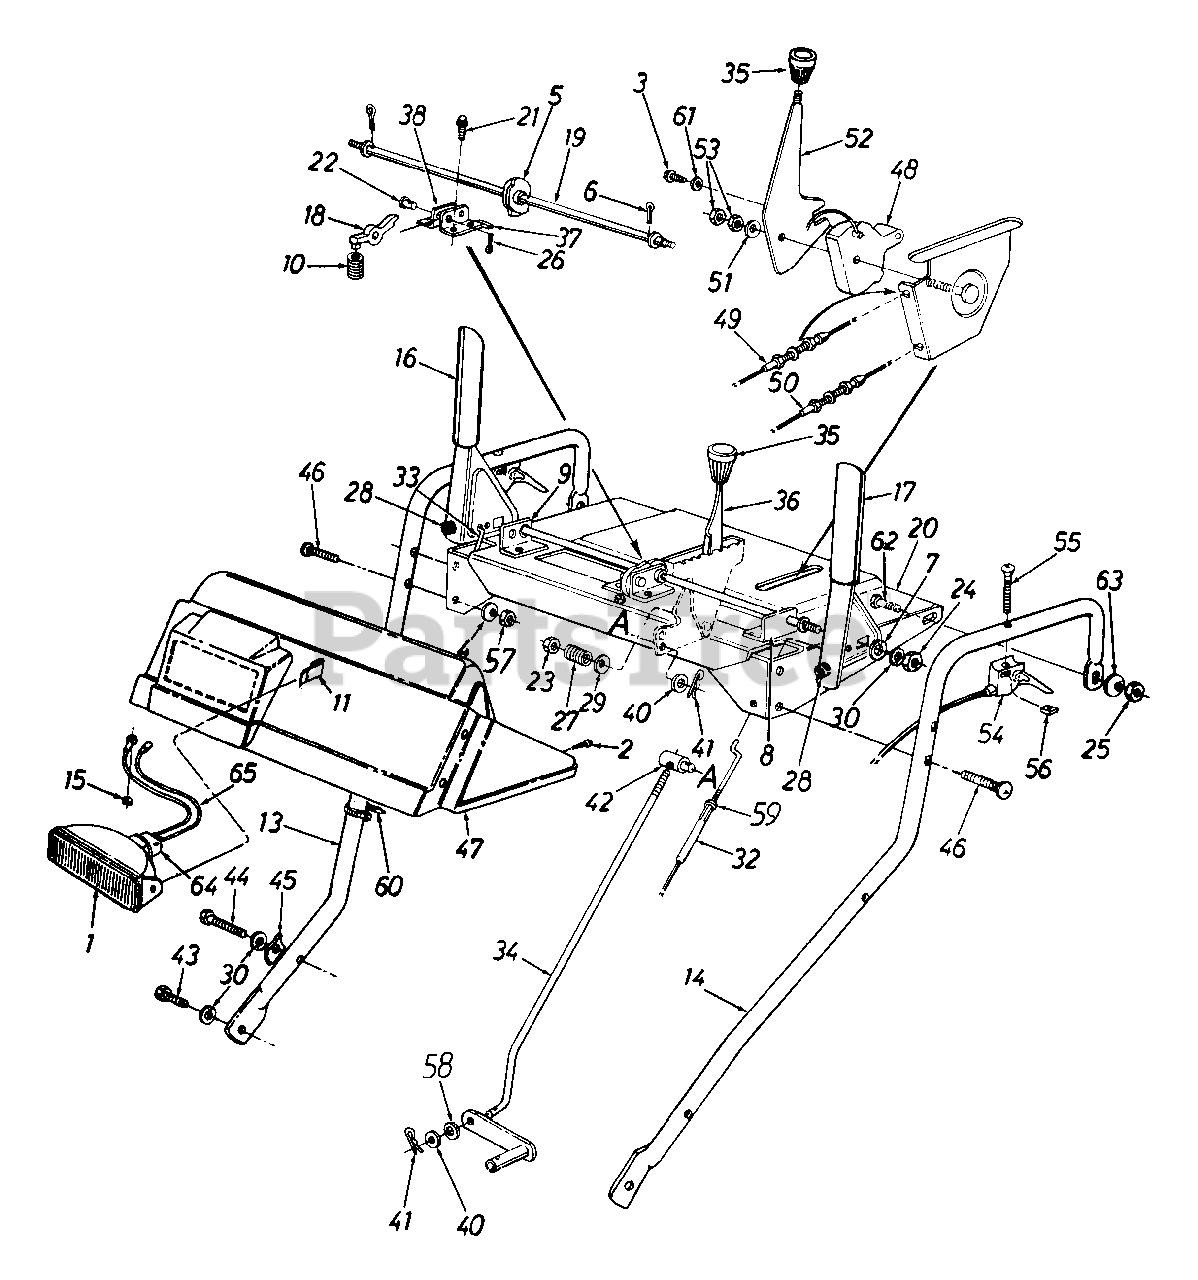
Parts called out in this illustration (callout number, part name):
1	Lamp Housing w/Lens
2	Truss Mach. B-Tap Scr. #10 x .5
3	Hex AB-Tap Scr. 1/4 x .62" Lg.
4	Bell-Wash. .325" I.D. x .88" O.D.
5	Cam Handle Lock
6	Cotter Pin 3/32" Dia. x .75" Lg.
7	Washer (Special) .72" O.D.
10	Compression Spring
11	Retaining Clip
13	Handle - R.H.
16	Engagement Handle - R.H.
17	Engagement Handle - L.H.
18	Pawl Handle Lock
22	Clevis Pin .437" Dia. x .65" Lg.
23	Hex Ins. L-Nut 3/8-24 Thd.
24	Hex Nut 5/16-18 Thd.
25	Hex Nut 1/4-20 Thd.
26	Cotter Pin 3/32" Dia. x 1" Lg.
27	Compression Spring
28	Rubber Bumper
29	Bell-Wash. .38" I.D. x .88" O.D.
30	L-Wash. 5/16" I.D.
32	Auger Clutch Cable
33	Drive Clutch Cable
34	Shift Rod
35	Shift Knob
36	Shift Handle
40	Fl-Wash. .344" I.D. x .62" O.D.
41	Internal Cotter Pin 5/16" Dia.
42	Ferrule
43	Hex Bolt 5/16-18 x .62" Lg. (Special)
44	Hex Bolt 5/16-18 x 1.75" Lg. (Gr. 5)
45	Handle Tab
46	Curved Carr. Bolt 5/16-18 x 1.5" Lg.
47	Handle Panel
48	Cable Guide
49	Chute Control Cable
50	Chute Control Cable w/Clip
51	Bell-Wash. .325" I.D. x .93" O.D.
53	Hex Cent. L-Nut 5/16-18 Thd.
54	Track Steer Cable w/Trigger
55	Oval C-Sunk Hd. Scr. 10-24 x 1.375" Lg.
56	Flat Weld Nut #10-24 Thd
57	Hex Nut 5/16-18 Thd.
58	Spr. Wash. .32" I.D. x .62" O.D.
59	Hex Nut #10-24 Thd.
61	Washer (Special) 1.25" O.D.
62	Hex Bolt 1/4-20 x .85" Lg.
63	Bell-Wash. .265" I.D. x .75" O.D.
64	Bulb
65	Wire Harness
